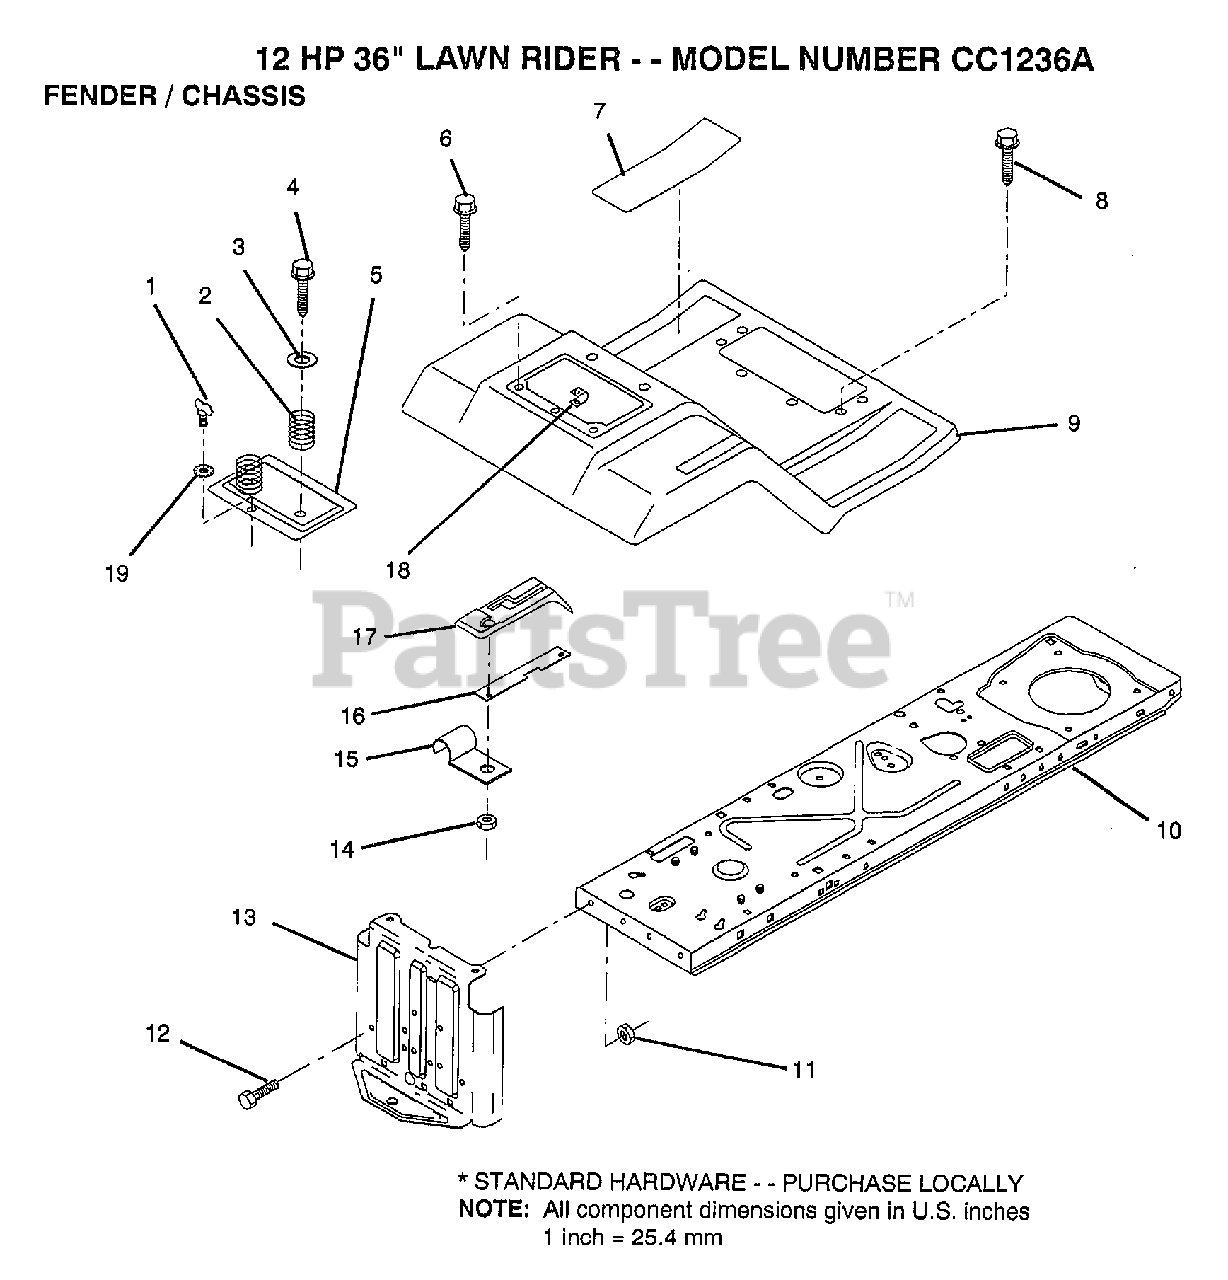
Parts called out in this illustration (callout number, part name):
1	STUD.1/4.TURN
2	SPRING COMPRESSIO
3	WASHER
4	SCREW
6	SCREW LT
7	PAD FOOTREST
8	SCREW
9	FENDER/FOOTREST
10	FRAME ASS'Y
12	BOLT
13	DRAWBAR
14	NUT
15	"CLIP,INSULATOR"
18	RECEPTACLE LT
19	RETAINER LT
